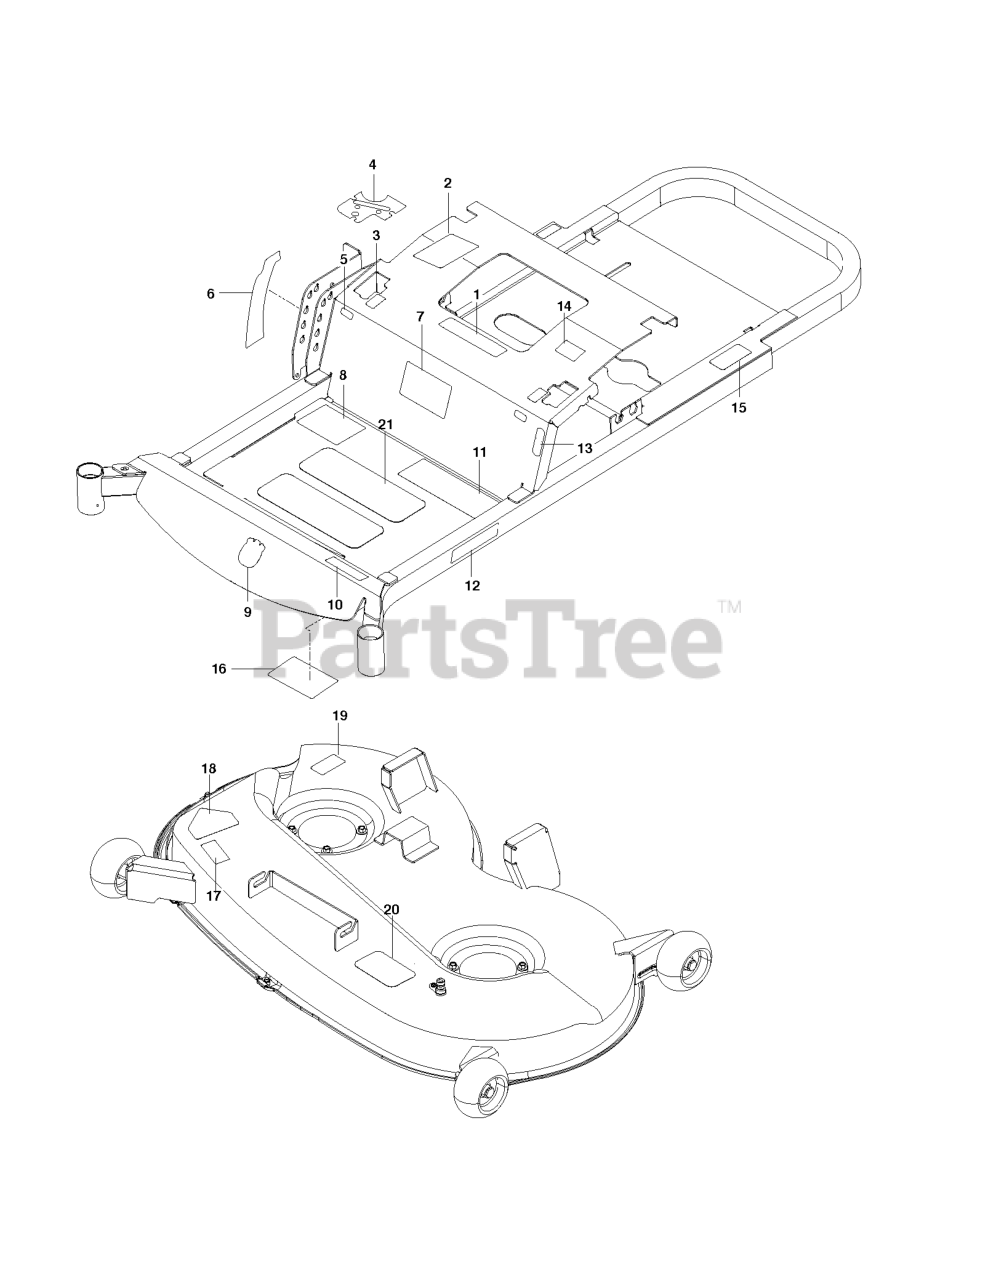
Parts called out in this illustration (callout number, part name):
1	EURO DECAL-BATTERY WARNIN6
2	DECAL, CUSTOMER RESPNSIBILITY
3	DECAL, MOTION CONTROL
4	DECAL, CTRL PANEL, HUSQ
5	DECAL, F.S.T.
6	DECAL, HEIGHT
7	DECAL, START
8	DECAL, WARNING
9	DECAL.AUGER.HUSQ.CROWN.SNOW
10	DECAL, RZ4623
11	DECAL, SAFETY WARNING
12	RP.DECAL.BADGE.170MM.TEXTLOGO
13	DECAL, PARK BRAKE
14	DECAL, EXITING MOWER
15	DECAL, DO NOT TOW
16	DECAL, SERVICE
17	DECAL, EURO SEVERING
18	DECAL, CPSC
19	DECAL, CAUTION
20	DECAL, BELT ROUTING
21	ANTI-SKID PAD
